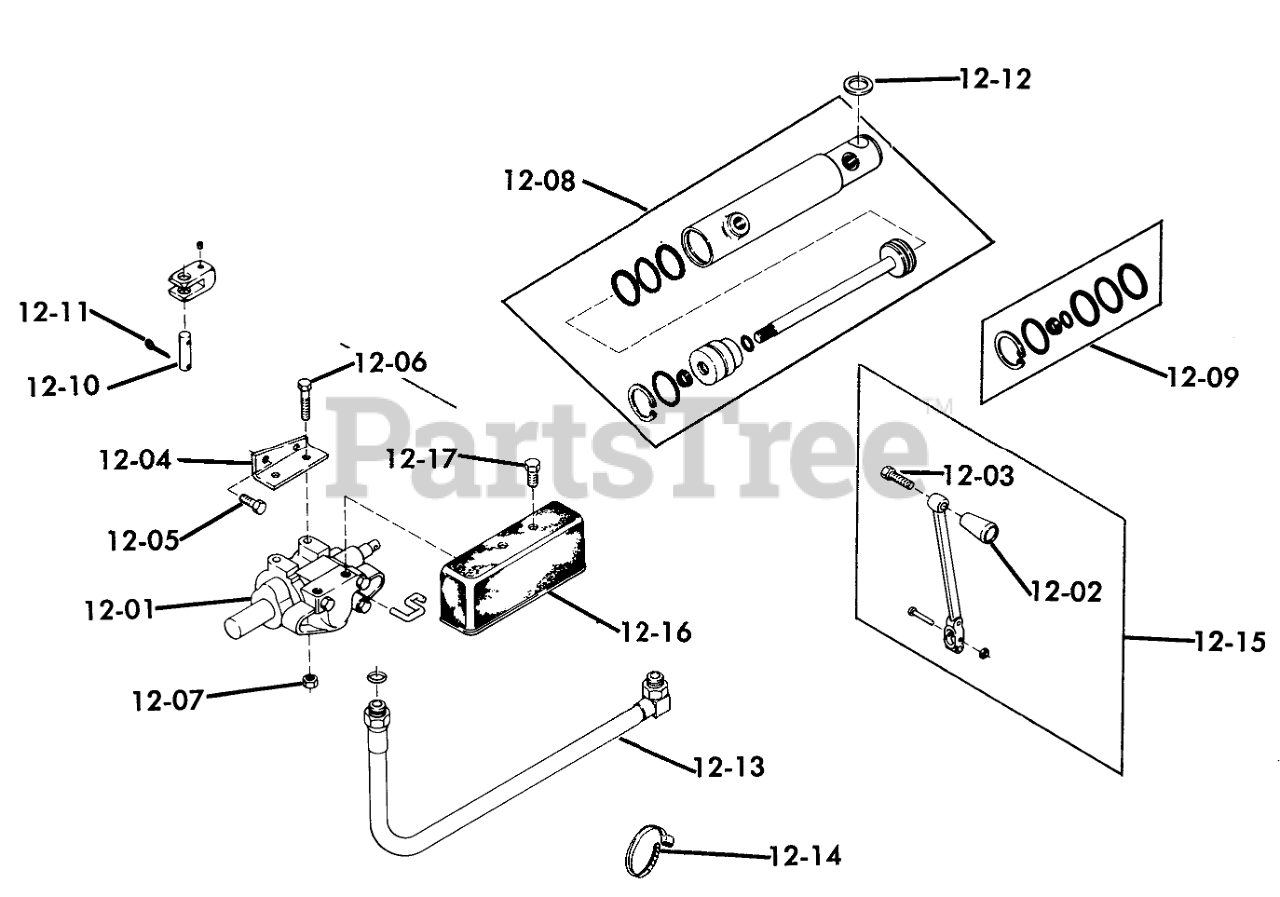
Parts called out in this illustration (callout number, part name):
12-01	Valve
12-01	Ring Kit
12-01	Spool Cap Kit
12-03	SCREW
12-04	SUPPORT-VALVE
12-05	Bolt
12-06	Bolt 1/4-20 X 1 1/2
12-07	Nut
12-08	CYLINDER ASSY R
12-09	S/A O-RING&GASKET AS
12-10	PIN
12-12	Spacer
12-13	16" Hose Assembly
12-13	HOSE HYDRAULIC 19"
12-13	ASSY-HYDRAULIC HOSE
12-13	HYD HOSE ASSY
12-14	PLASTIC TIE
12-15	Assy-Handle
12-16	Cover-Valve
12-17	Bolt
